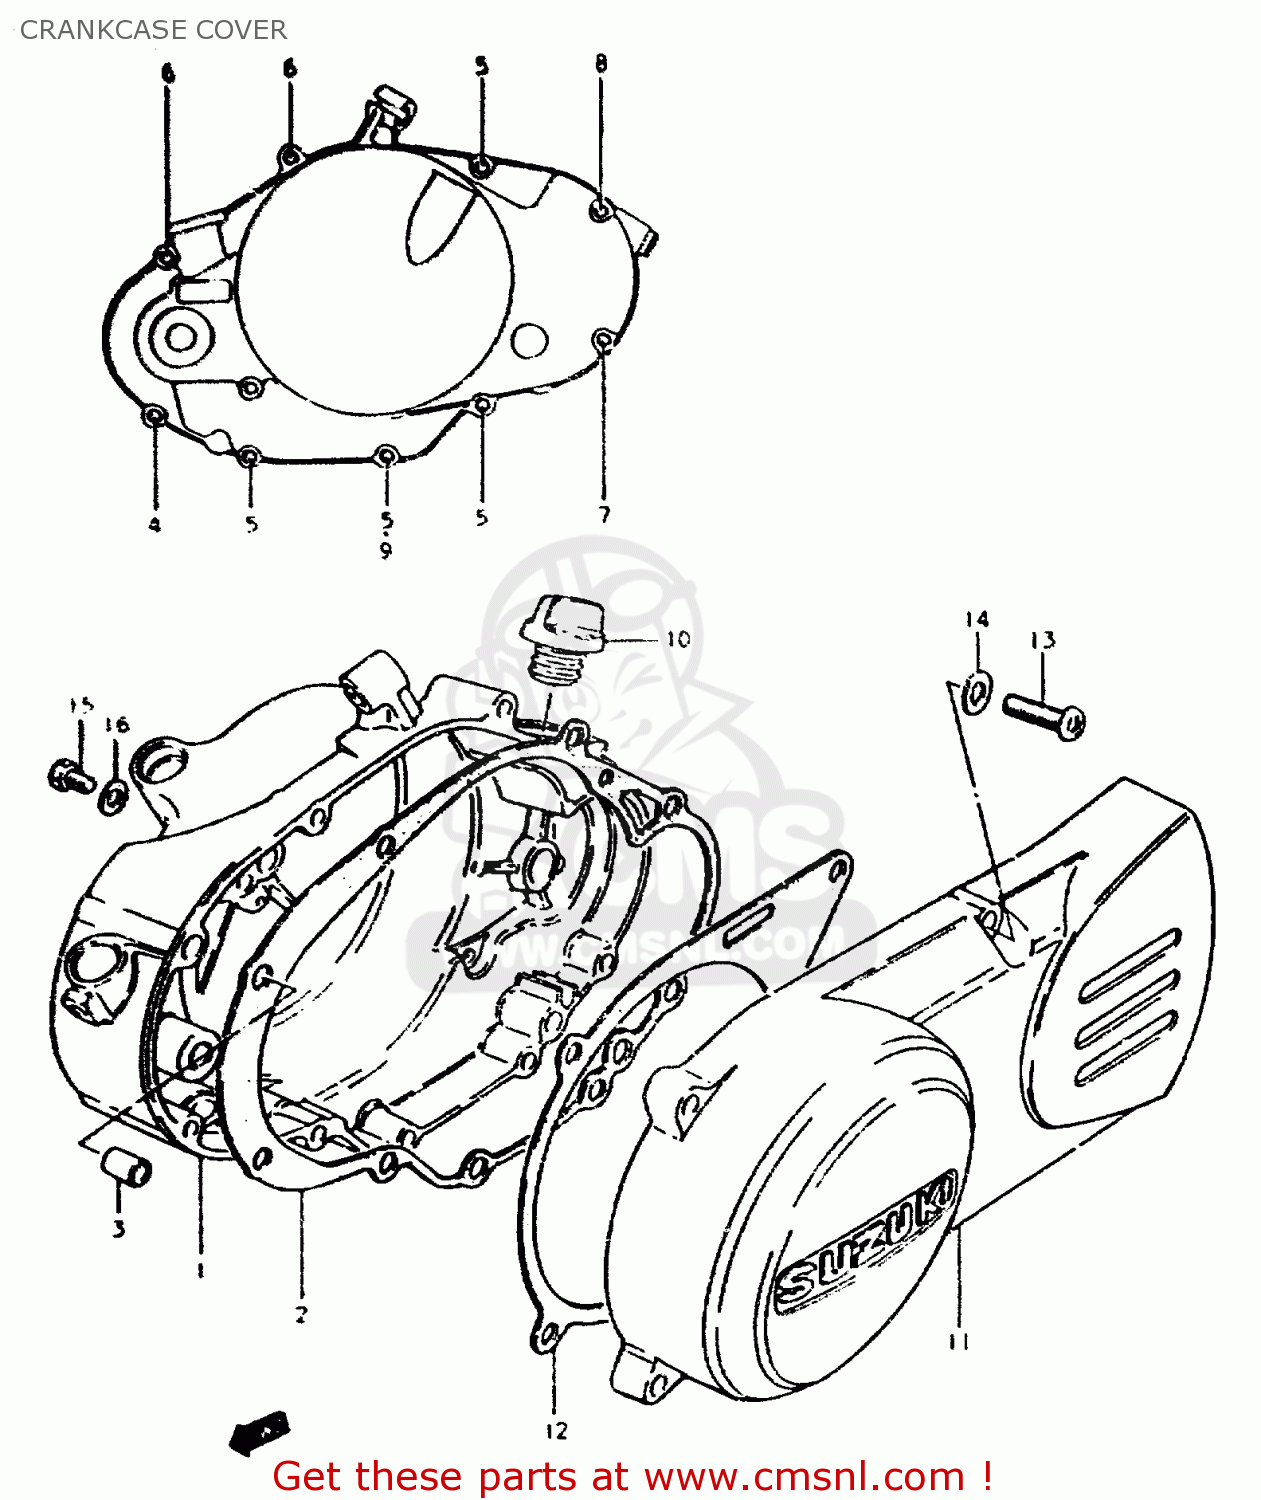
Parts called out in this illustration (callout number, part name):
1	COVER SET,CLUTCH
2	GASKET,CLUTCH COVER (MCA)
3	PIN
4	SCREW
5	SCREW 6X30
6	SCREW
7	SCREW
8	SCREW 6X60
9	GASKET(6.2X11X1).2 (NAS)
10	PLUG
11	COVER, MAGNETO
12	GASKET,MAGNETO COVER (NAS)
13	SCREW
14	WASHER 6MM
15	SCREW(6X10)
16	GASKET(6.2X11X1) (NAS)
